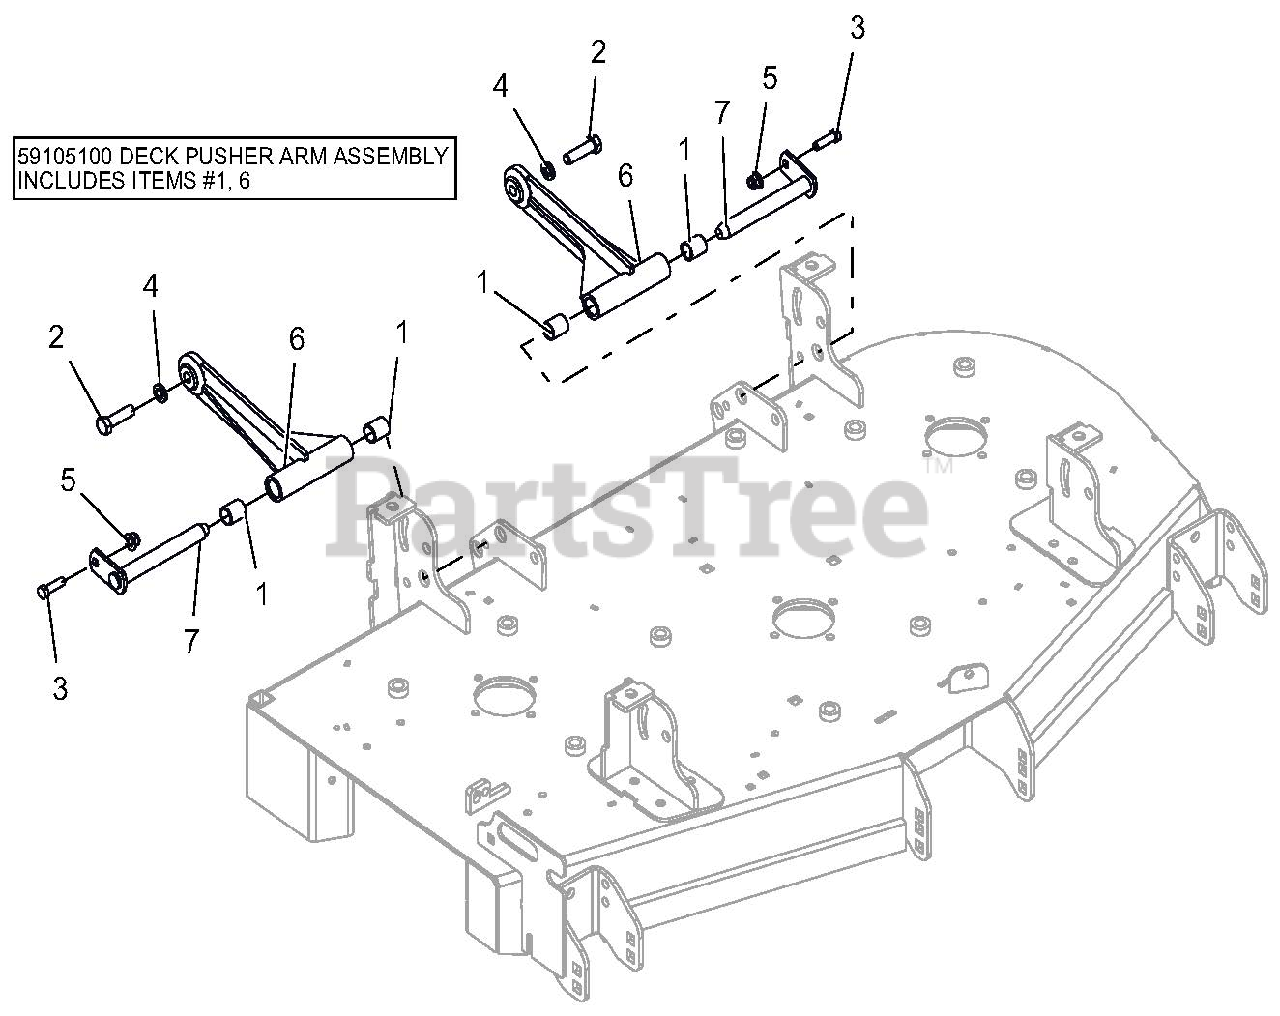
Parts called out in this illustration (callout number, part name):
1	BRG, .75 X .875 X 1.00
2	BLT-HEX .50-13X1.75 GR5 YWZC EP80
3	BLT-HEX .38-16X1.25 GR5 YWZC
4	WSHR-LK .50X.125 REG YWZC
5	NUT-LK-NYL-FLG .38-16 YWZC
6	WLDMT, DECK PUSHER ARM
7	WLDMT, MOWER MTG. PIN
8	DECK PUSHER ARM ASSEMBLY
